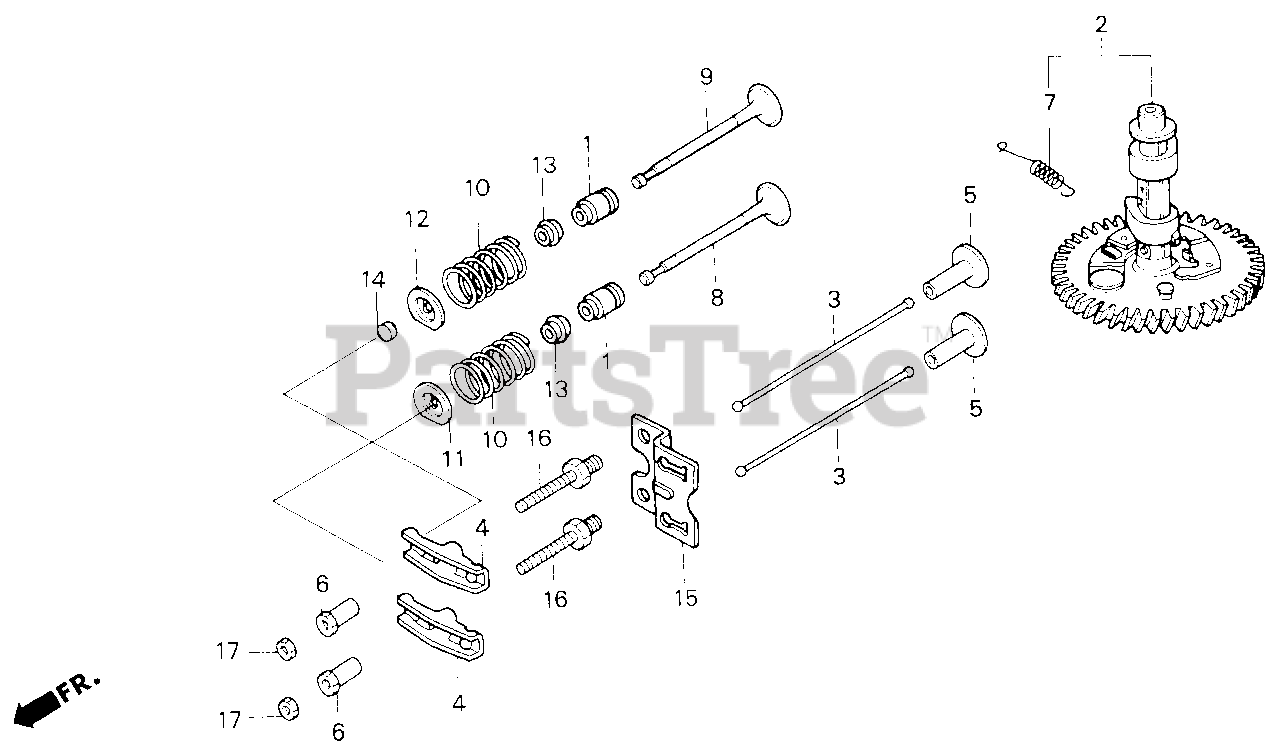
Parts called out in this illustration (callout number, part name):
1	SEAL, VALVE STEM
2	CAMSHAFT ASSY.
2	CAMSHAFT
3	ROD, PUSH
4	ARM, VALVE ROCKER
5	LIFTER, VALVE
6	PIVOT, ROCKER ARM
7	SPRING, WEIGHT RETURN
8	VALVE, IN.
9	VALVE, EX.
10	SPRING, VALVE
11	RETAINER, IN. VALVE SPRING
12	RETAINER, EX. VALVE SPRING
13	SEAT, VALVE SPRING
14	ROTATOR, VALVE
15	GUIDE, PUSH ROD
16	BOLT, PIVOT (8MM)
17	NUT, PIVOT ADJ.
